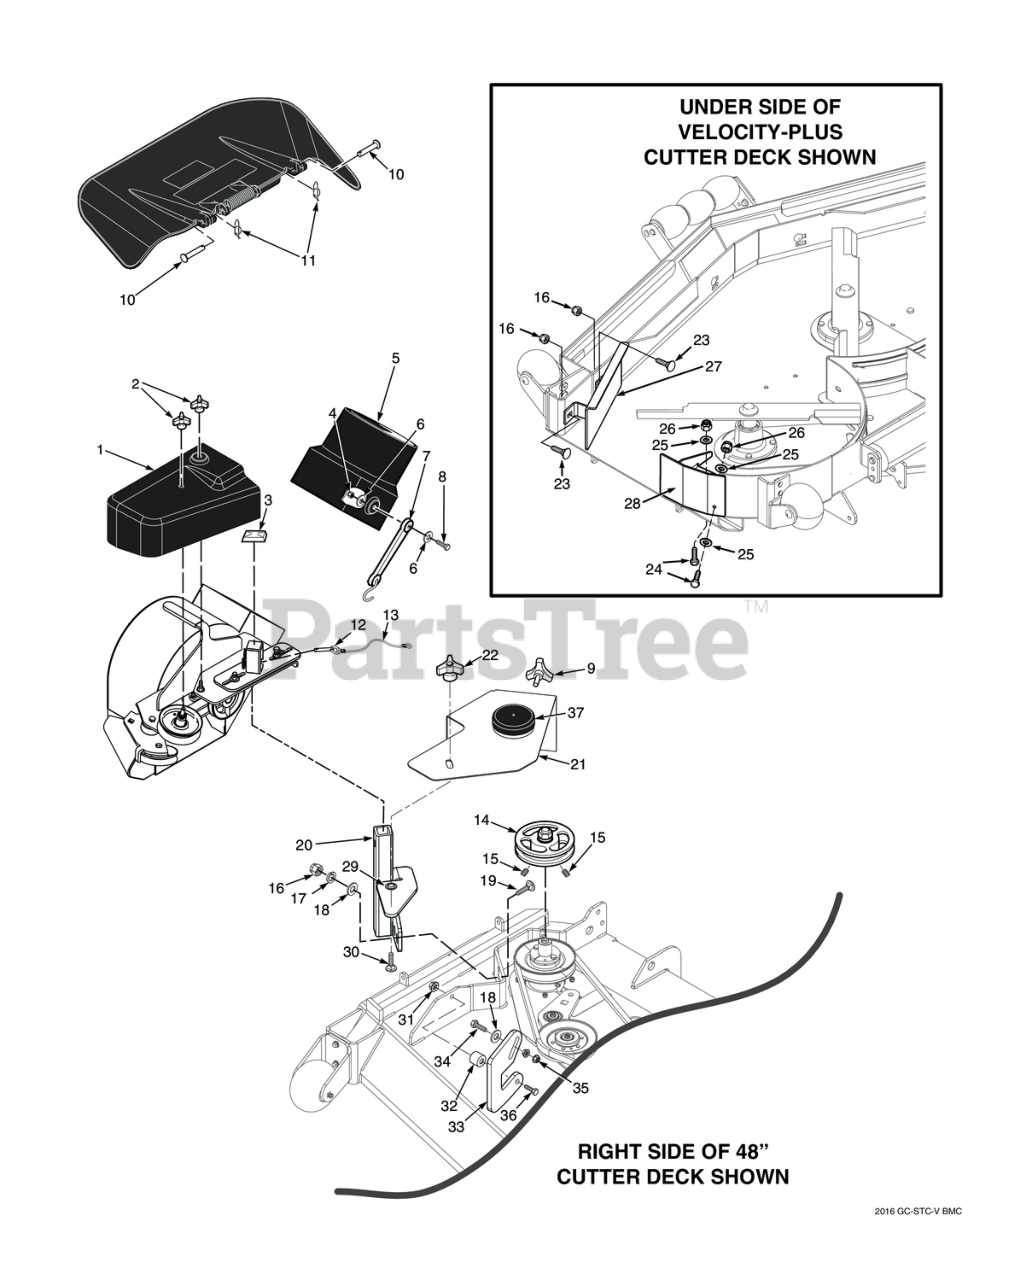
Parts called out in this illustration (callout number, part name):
1	Belt Cover, 48"
1	Belt Cover, 52"
2	Wing Nut, 3/8-16 (Small) Top side
3	Cap, Square Vinyl
4	HEX, NUT, ELASTIC STOP LOCK, 1/4-20
5	Adapter, Blower GC-STC,
6	Flatwasher, 1/4" (.312 x .750 x .065")
7	Rubber Strap 7-3/4"
8	SERR. FLG. HEX HEAD CAPSCREW, 5/16-18 X 3/4
9	Knob, w/stud 3/8-16 x 1-1/4"
10	Clevis Pin, 5/16 x 1-1/2"
11	Pin, Rue Cotter 5/16 Dia.
12	Pin, Ring 1/2 x 2-1/4"
13	Lanyard, Deck Height Pin
14	Pulley, 4.0" Dia. - 1.125" Bore, (STT-52 & STTII-52)
15	Setscrew, Hex Socket Knurl Cup Pt. 5/16 - 18 (nylock)
16	HEX NUT, ELASTIC STOP LOCK, 3/8-16
17	Lockwasher, 3/8" Spring, Kawasaki FX / FS
18	Flatwasher, 3/8" Special (.391 x .938 x .105)
19	SHORT SQ. NECK CARRIAGE BOLT, 3/8-16 X 1-1/4"
20	Mounting Post Weldment, Blower, (61")
21	Belt Cover Assembly, w/Cap - 48"
21	Belt Cover Assembly, w/Cap - 52"
22	Wing Nut, 3/8-16 (Small) Top side
23	Carriage Bolt, 3/8-16 x 1.0"
24	Bolt, Heax Head 5/16-18 x 1" (48V / 52V)
25	Flatwasher, 5/16-.375 x .875 x .083 (35BV & 37BV-EFI)
26	HEX NUT, ELASTIC STOP LOCK, 5/16-18
27	Baffle Weldment, 52V Deck
28	Baffle, Turbo 48" Deck
28	Baffle, Turbo 52" Deck
29	Nut, Push-On - 3/8" Dia.
30	Carriage Bolt, 3/8-16 x 1-1/4"
31	NUT, 3/8-16 SERRATED FLANGE HEX HEAD
32	Spacer (STCII48 & SCZ48)
33	Bracket (STCII48 & SCZ48)
34	Bolt, Hex Head 3/8-16 x 1-1/2" Grade 8 Black
35	NUT, 3/8-16 SERRATED FLANGE HEX HEAD
36	Bolt, Hex Head 3/8-16 x 1-3/4" (Kohler EFI)
